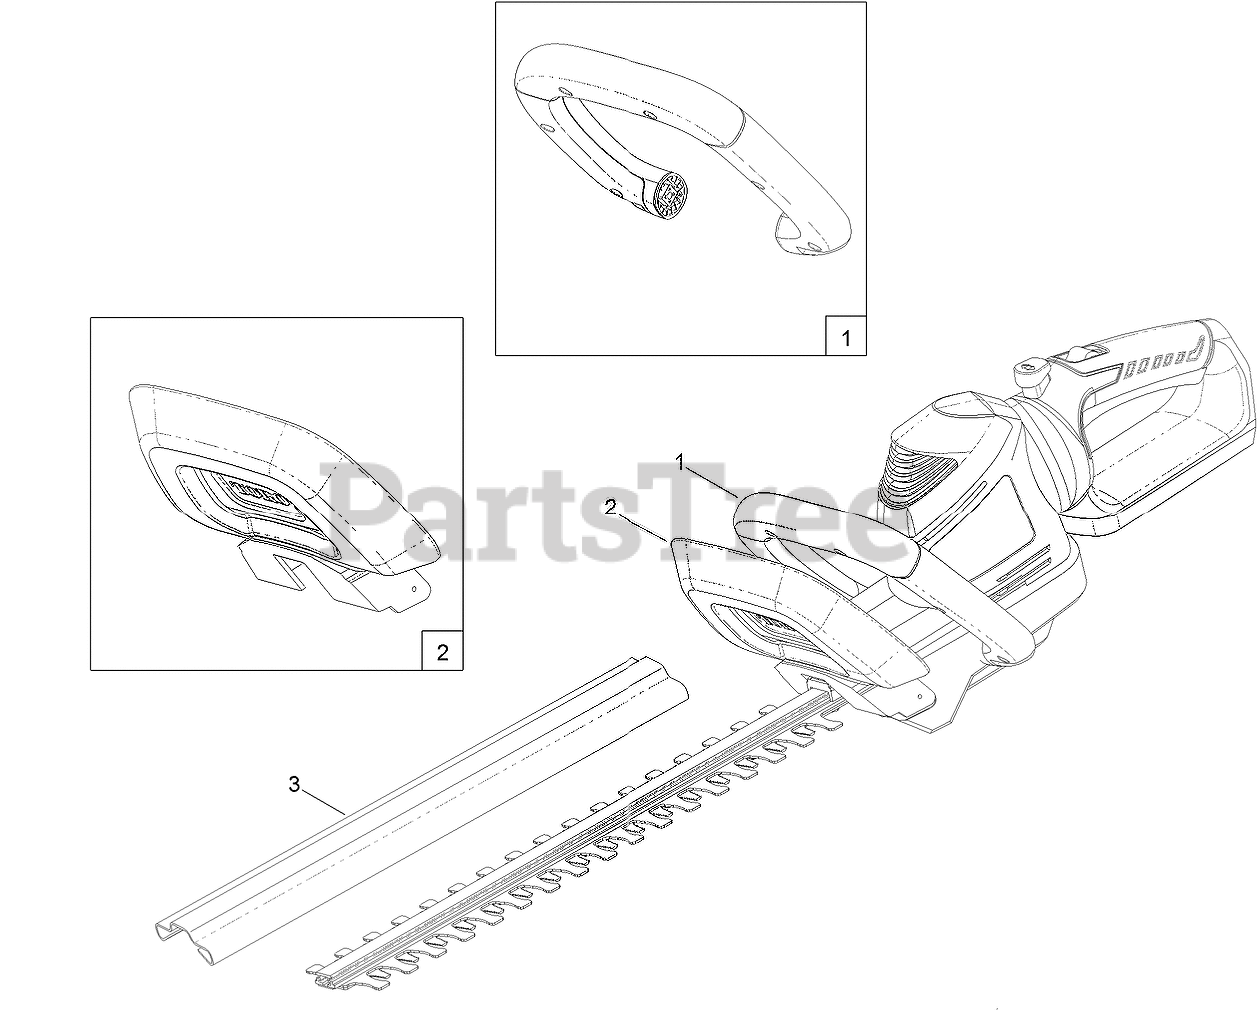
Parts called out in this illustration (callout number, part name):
1	HANDLE-ASSIST
2	GUARD-TRIMMER, HEDGE
3	GUARD-TRIMMER
